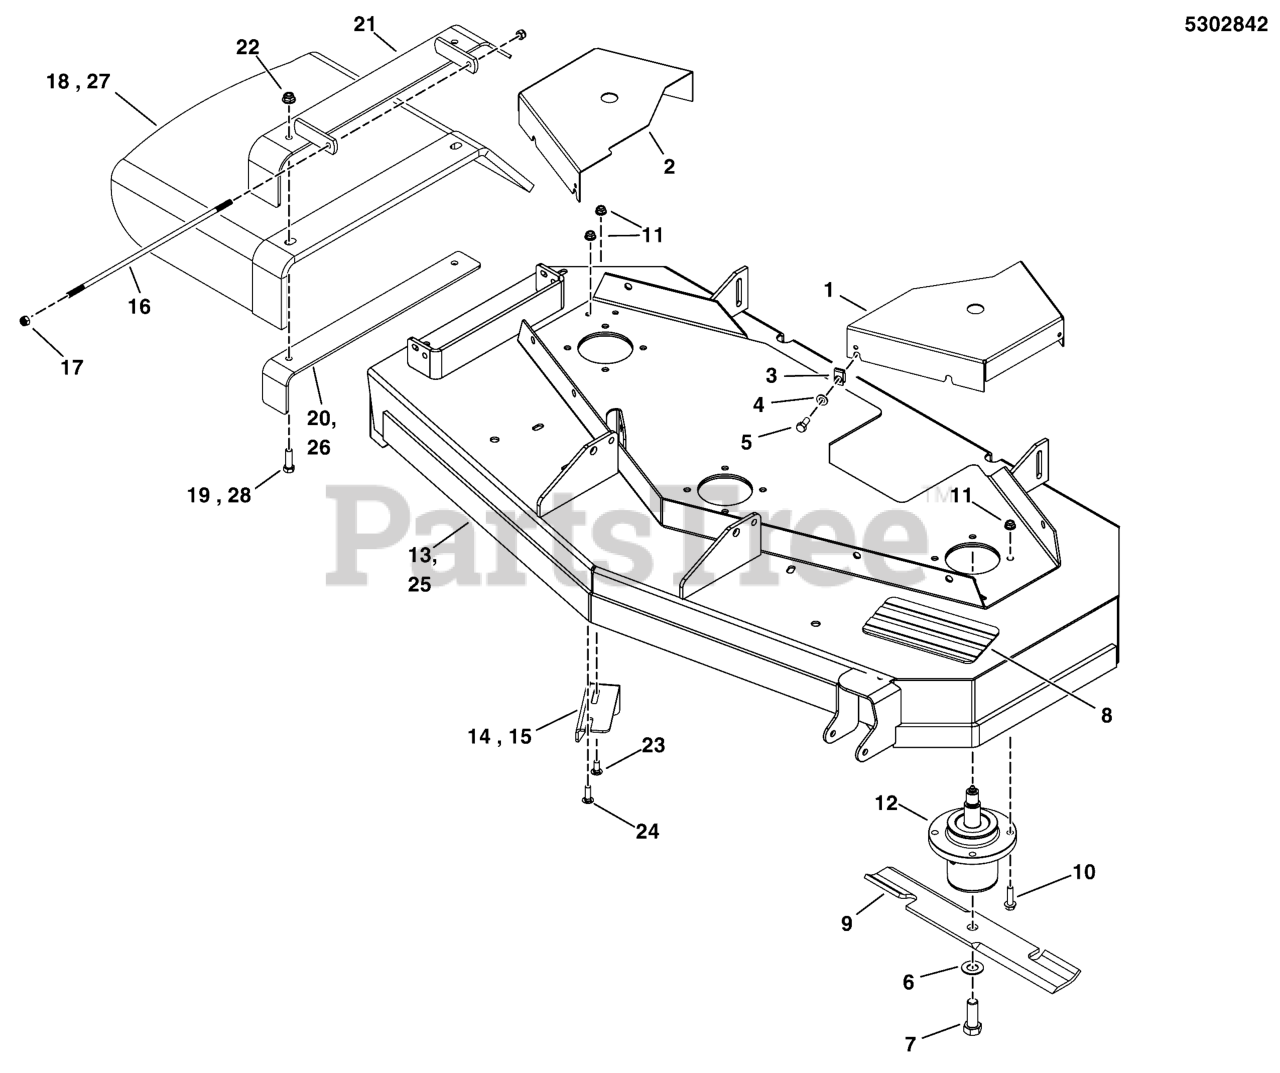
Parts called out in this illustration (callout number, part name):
1	GUARD, 48" MOWER DECK, LH
2	GUARD, 48" MOWER DECK, RH
3	BODY CLIP, 5/16-18-7GA MATERIAL
4	WASHER, 5/16" SAE
5	BOLT, 5/16-18 X 3/4 GD5
6	WASHER, 5/8 USS
7	BOLT, 5/8-11 X 1-3/4 GR8
8	SAFETY WALK, 4.00 X 7.50
9	BLADE, 16.25"
10	BOLT, 5/16-18 X 1-1/4" FLANGE
11	NUT, 5/16-18 HEX NYLOCK FLANGE
12	ASSM, SPINDLE, LOW PROFILE
13	DECK SHELL W/ DECALS, F50XT - 48"
14	WELD, DISCHARGE BAFFLE, 48" - BLK
15	PLATE, DEFLECTOR - BLK
16	ROD, BRAKE LINKAGE
17	NUT, 5/16-24 HEX NYLON LOCK
18	CHUTE, RUBBER, BENT
19	BOLT, 3/8-16 X 1-1/2" GD5 CZ
20	SUPPORT, DISCHARGE CHUTE, 44/48/52 - BLK
21	WELD, MOUNT, DISCHARGE CHUTE - BLK
22	NUT, 3/8-16 HEX NYLOCK FLANGE
23	BOLT, 5/16"-18 CARRIAGE, 3/4"
24	BOLT, 5/16"-18 CARRIAGE, 1"
25	DECK SHELL W/ DECALS, F50XT - 48
26	SUPPORT, DISCHARGE CHUTE - BLK
27	CHUTE, RUBBER DISCHARGE (5104441)
28	BOLT, 3/8-16 X 1-1/2, CARRIAGE, GD5, CZ
